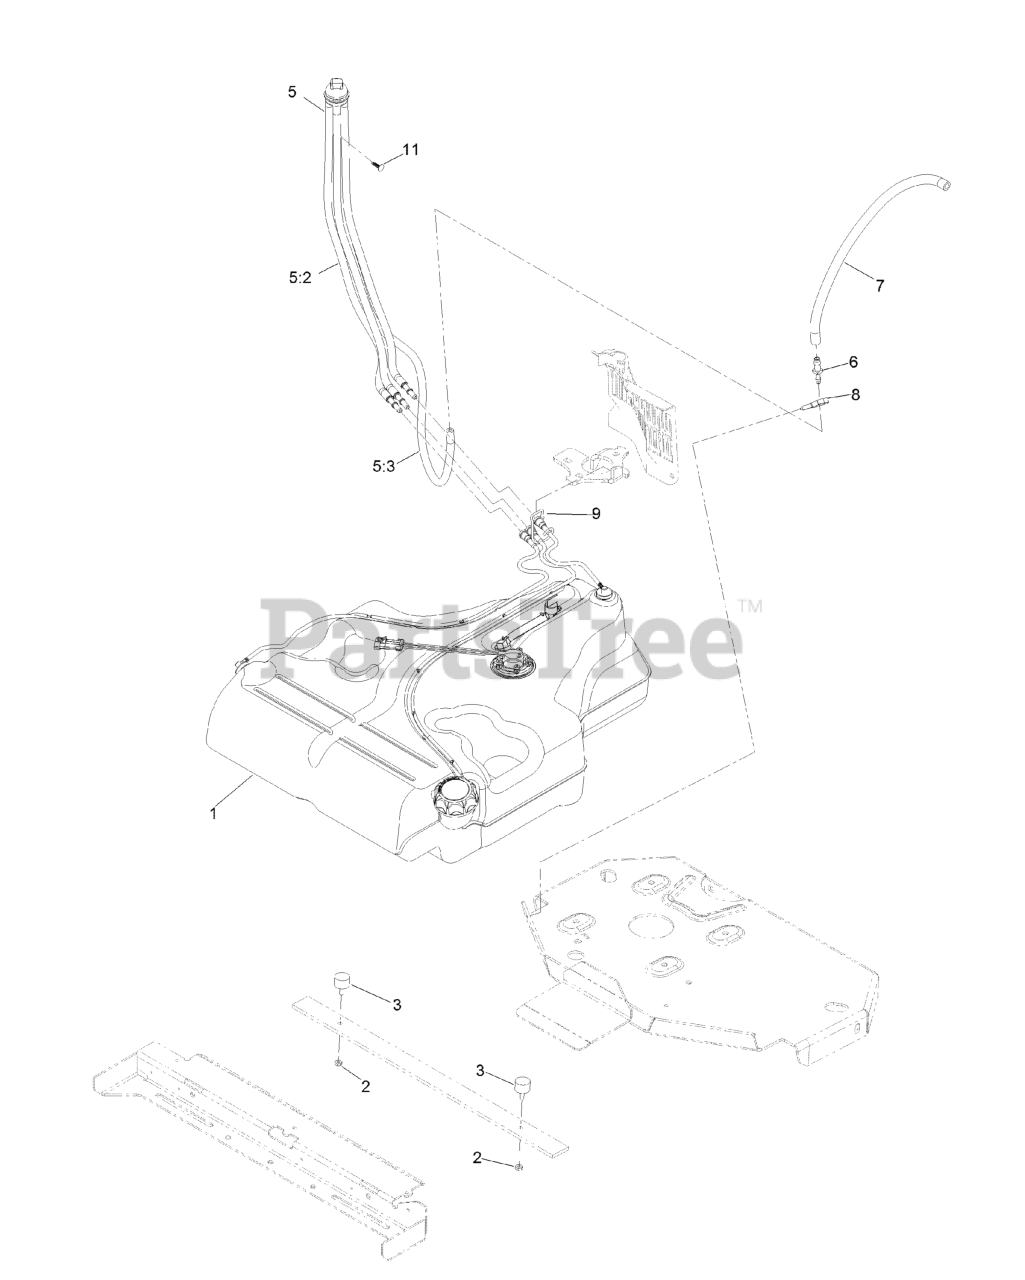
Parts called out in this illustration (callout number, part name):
1	FUEL TANK ASM
2	NUT-JAM
5	FUEL MANIFOLD VENT ASM
5:2	HOSE-FUEL
5:3	HOSE-FUEL
6	FITTING-STRAIGHT
7	HOSE-FUEL
8	CLAMP-HOSE
9	RETAINER-LINE, VAPOR
11	PLUG-PLASTIC
